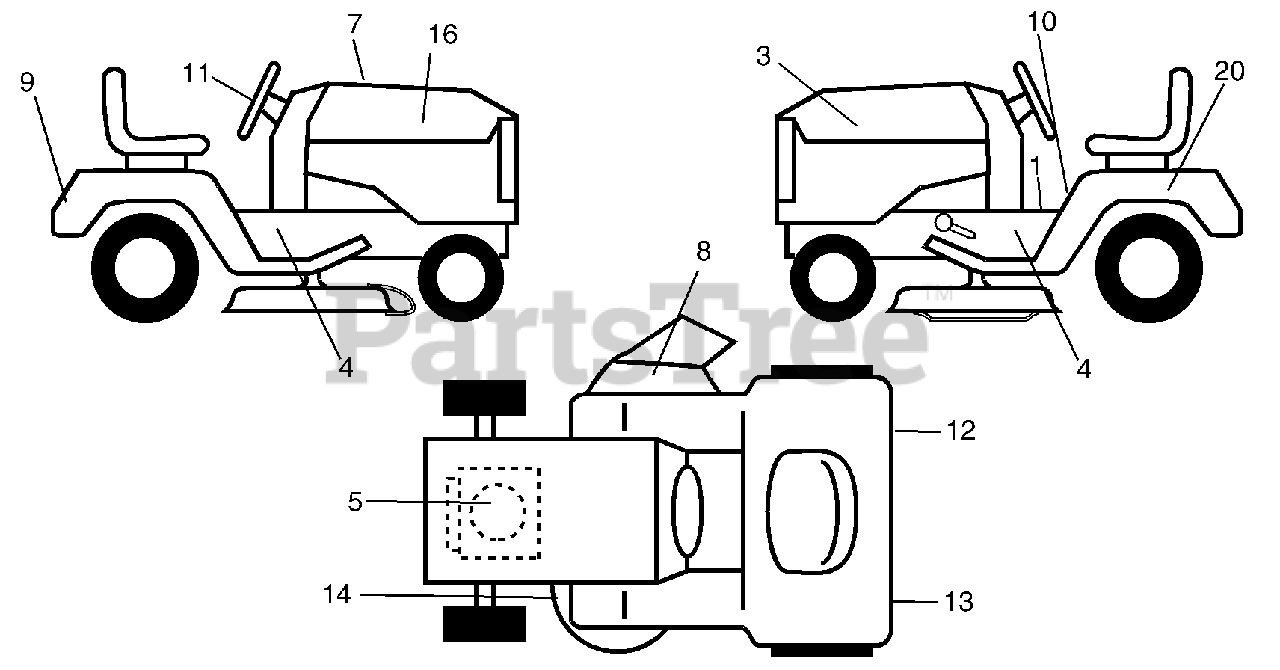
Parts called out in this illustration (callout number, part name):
1	Decal Oper
3	Decal Hood LH
4	Decal Chassis
5	Decal HP Engine
7	Decal Replacement Parts
8	Decal Deck "B" 42"
9	Decal Fender Logo
10	Decal Fender Danger
11	Decal Ins Strg Whl
12	Decal Fend Reflector Rh
13	Decal Fend Reflector Lh
14	Decal V-Belt Schematic
16	Decal Hood Rh
20	Decal Bat Dan/Psn
